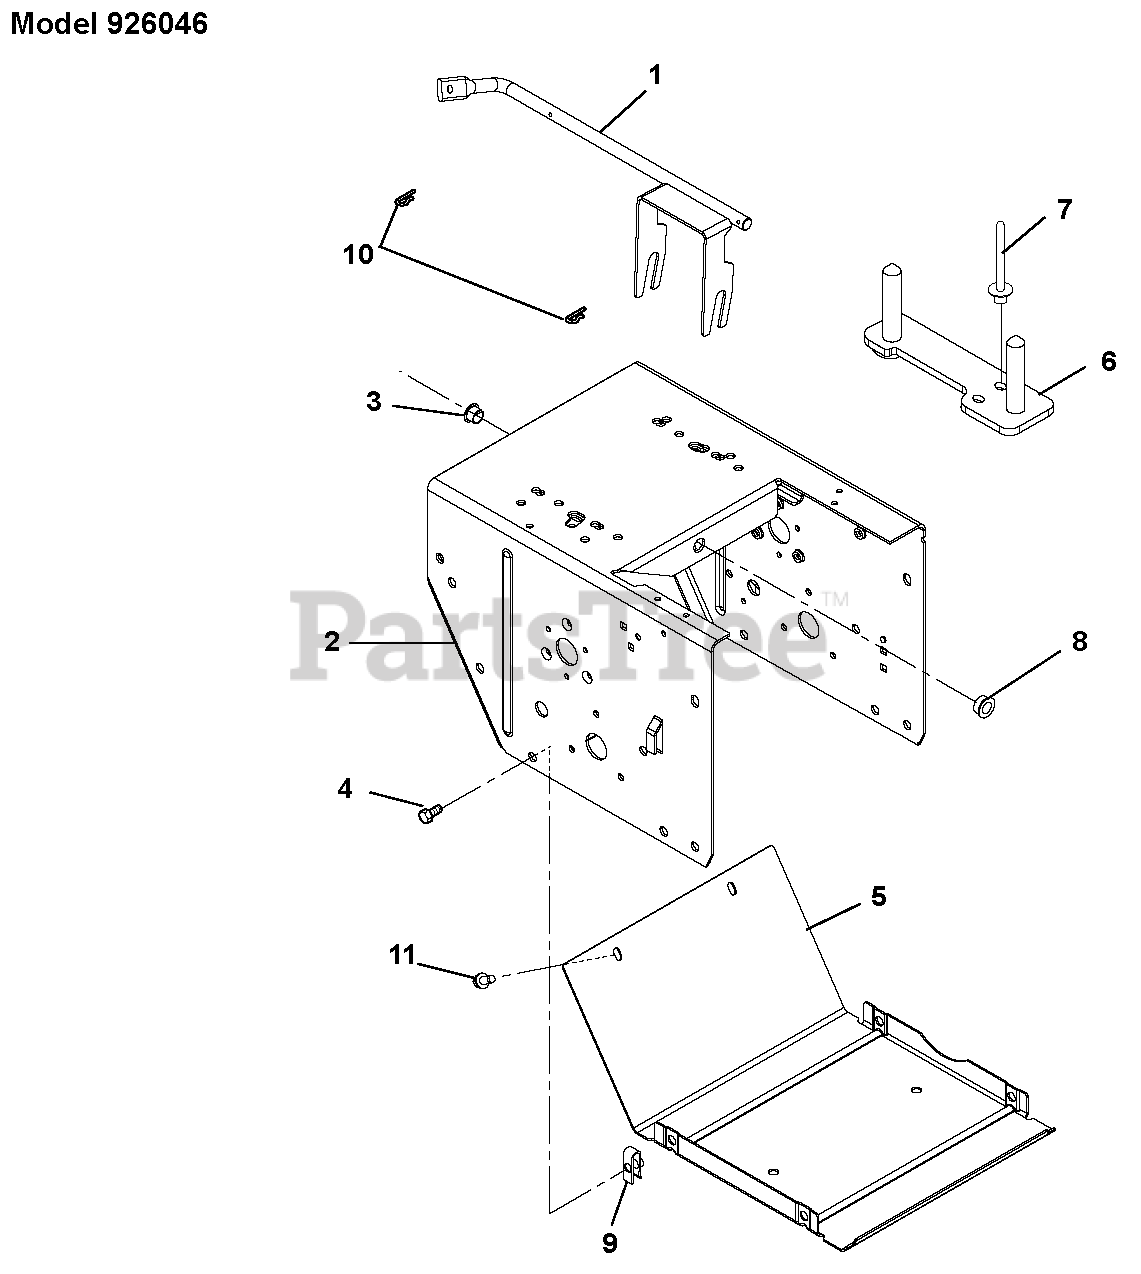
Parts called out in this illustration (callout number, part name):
1	Arm, Shift
2	Main Frame
3	Bushing, Polyliner
4	Bolt, Hex Washer Head .25-20 x .75
5	Cover, Bottom
6	Strap, Engine Bolt
7	Rivet, Pop .187
8	Bushing, Polyliner
9	Nut, Retainer .25-20 x .56
10	Clip, Spring
11	Screw, Tapping Hex Washer Head Thread Rolling .25-20 x .50
